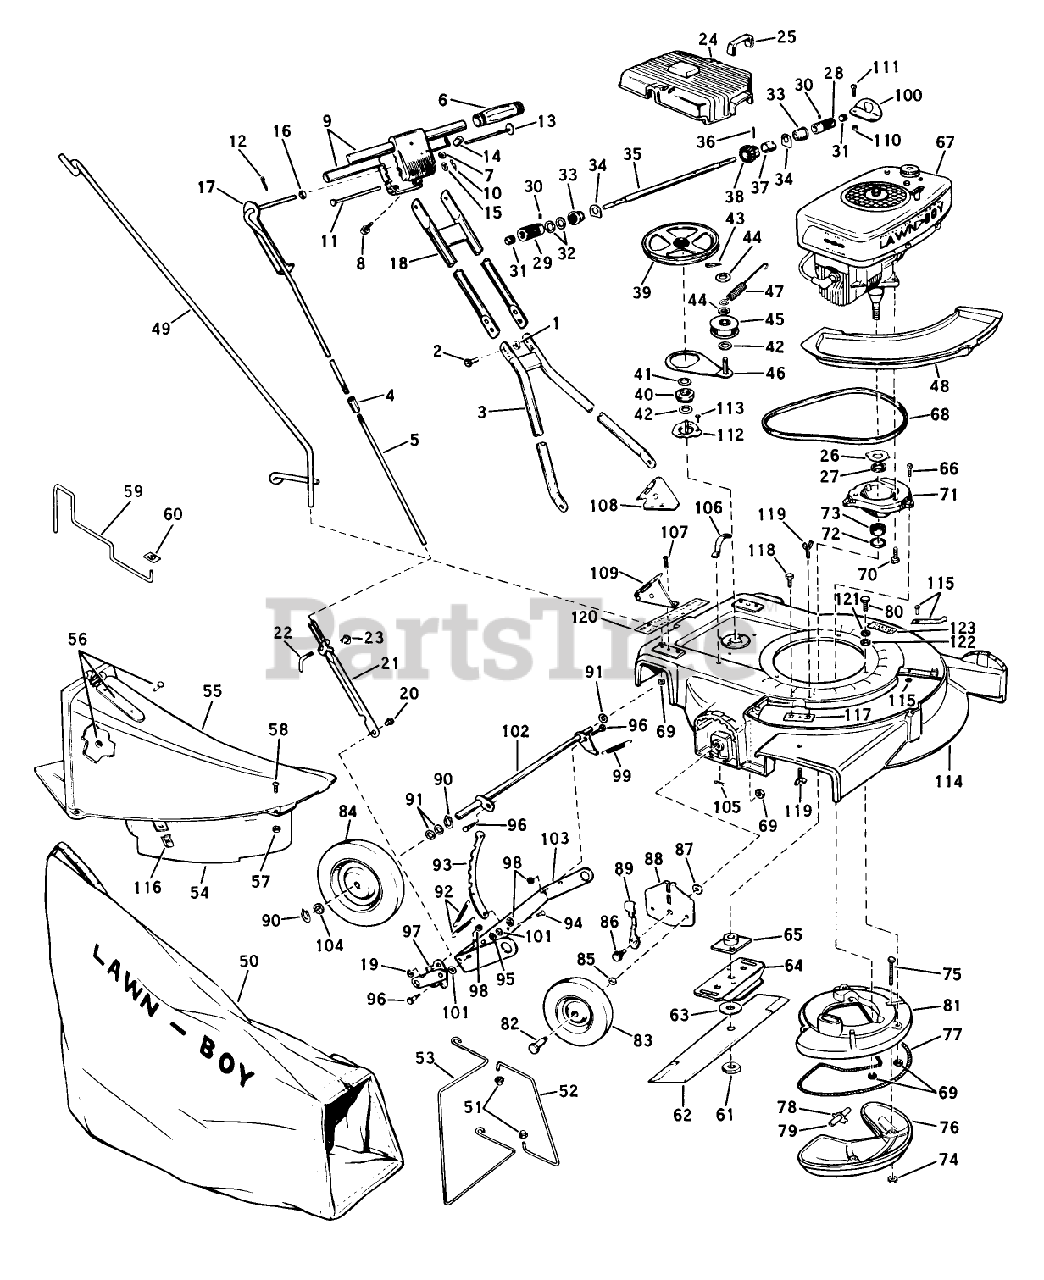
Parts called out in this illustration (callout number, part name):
1	STOP NUT
12	Pin-Cotter
31	GREASE PLUG
40	Felt-Oiler (Cup)
51	Nut-Self Threading
52	Frame, Left-Bag
54	Skirt Assembly-Chute (Includes Hardware)
55	Chute and Spring Assy. (Includes Hardware)
61	NUT-BLADE
65	PLATE AND COLLAR ASM
74	LOCKNUT E
78	Gasket-Internal Tube
79	Tube-Internal Muffler
82	BOLT WHEEL
85	WASHER WROUGHT
90	RETAINING RING
96	BOLT RB&W
98	STOP NUT
101	WASHER S
110	STOP NUT
115	Spring, Rivet Washer Assy.
116	SPEED NUT ARDEN
120	Decal, Instruction
